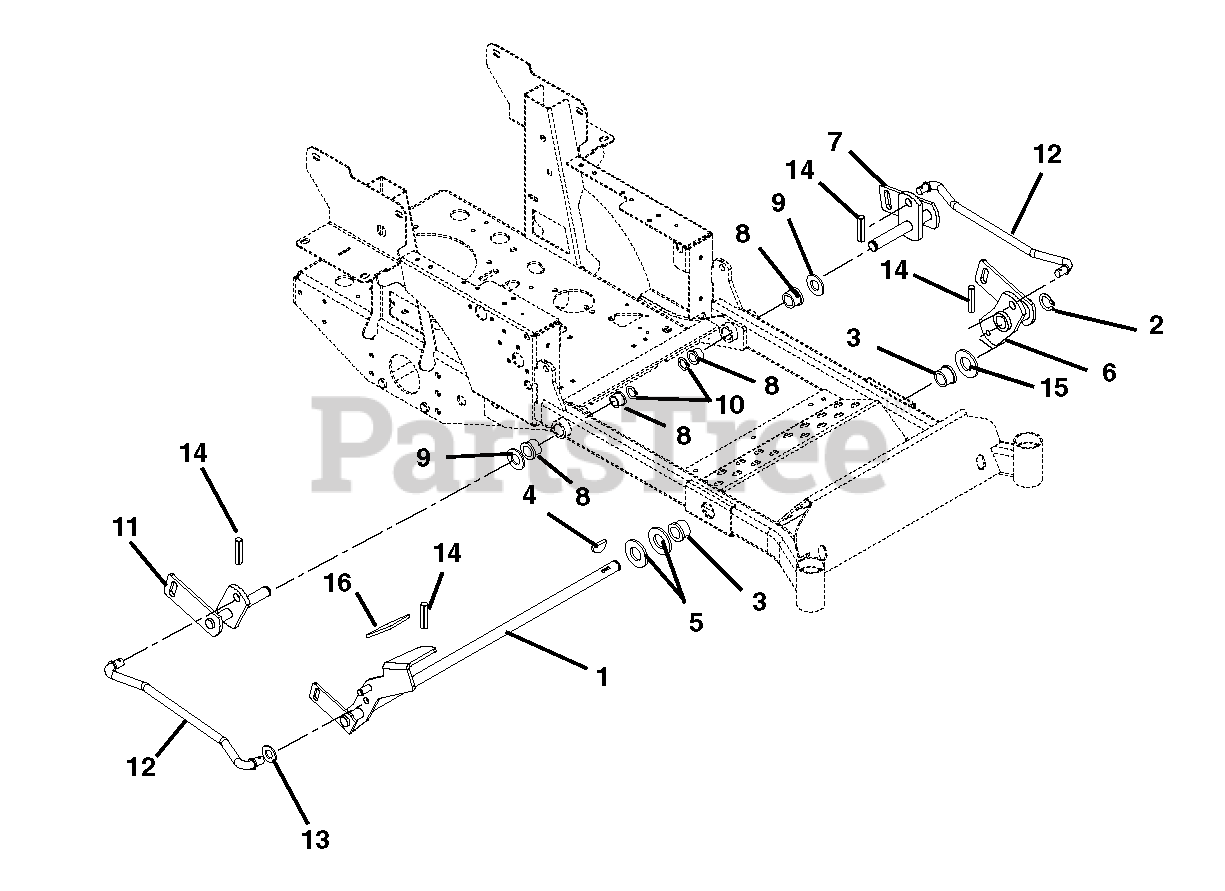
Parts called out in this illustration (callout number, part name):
1	Weldment, Mechanical Deck Lift
2	Ring, Retaining External 1.00 x .078
3	Bushing, Flange Nylon 1.020 x 1.385 x .75 x 1.75
4	Key, Woodruff .25 x 1.00
5	Washer, Flat Steel 1.062 x 2.0 x .134
6	Weldment, Left Hand Mower Lift Arm
7	Weldment, Left Hand Rear Mower Lift Arm
8	Bushing, Flange Nylon .762 x 1.0 x .580 x 1.48
9	Washer, Hardened Steel .758 x 1.23 x .031
10	Ring, Retaining External .689 x .077
11	Weldment, Right Hand Rear Mower Lift Arm
12	Rod, Lift Assist
13	Washer, Flat Steel .630 x 1.25 x .062
14	Pin, Roll .25 x 1.25 Stainless Steel
15	Washer, Hardened Thrust 1.00 x 1.55 x .03
16	Grip, Pedal
